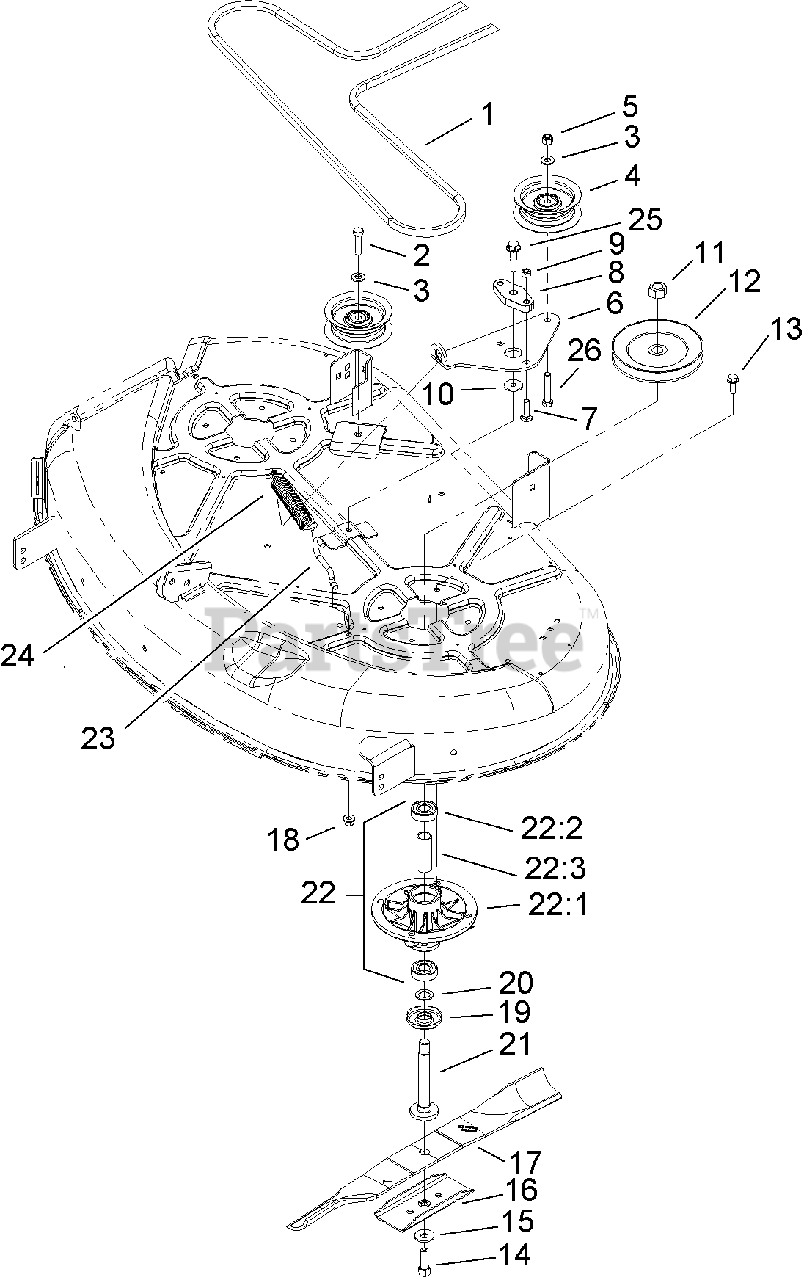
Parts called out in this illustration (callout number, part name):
2	SCREW-HH
3	WASHER-FLAT
4	PULLEY-IDLER, FLAT
5	NUT-LOCK, NI
6	ARM-IDLER
7	SCREW-CARR
8	BUSHING-PIVOT
9	NUT-LOCK, NI
10	WASHER-PIVOT
11	NUT-HEX
12	PULLEY
13	SCREW-TAPTITE
14	SCREW-BLADE
15	WASHER-BELLEVILLE
16	STIFFENER-BLADE
17	BLADE-21.6 INCH
18	NUT-LOCK, NI
19	SHIELD-BEARING
21	SHAFT-SPINDLE
22	Spindle ASM
22:1	HOUSING-SPINDLE
22:2	BEARING-BALL
22:3	SPACER-BEARING
23	HOOK-RETURN, SPRING
24	SPRING-EXTENSION
25	BOLT-SHOULDER
26	SCREW-HH
